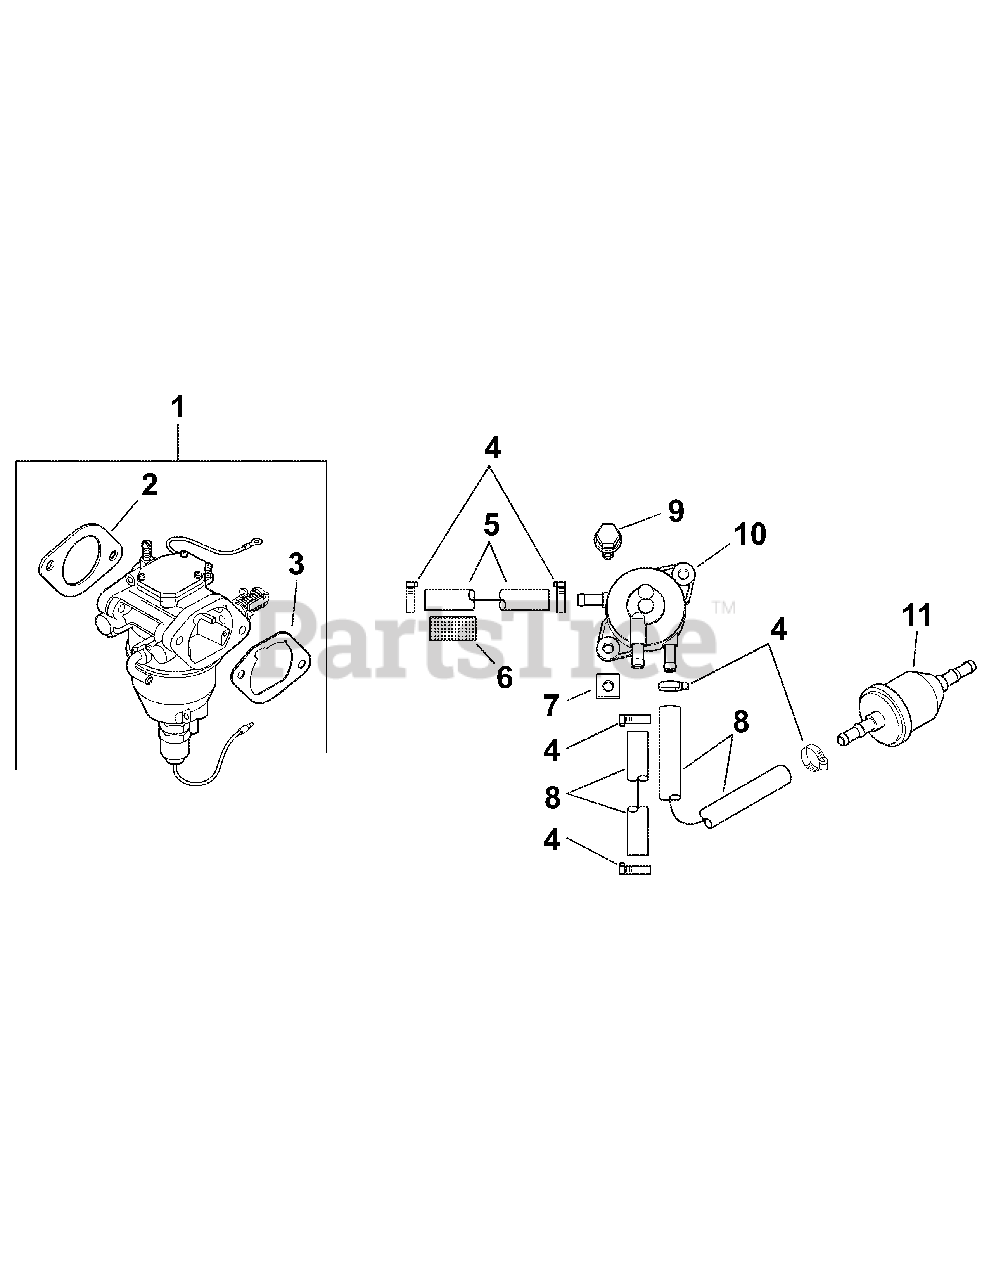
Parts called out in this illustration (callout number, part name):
1	KIT, CARBURETOR W/GASKETS
2	GASKET, CARBURETOR
3	GASKET, AIR CLEANER BASE
4	CLAMP, SPRING HOSE 1/2"
5	LINE, FUEL 11"
6	SLEEVE, INSULATING 14"
7	NUT, PLASTIC-BLACK
8	LINE, FUEL
9	SCREW, TAP M6X1.7X18
11	FILTER, FUEL
